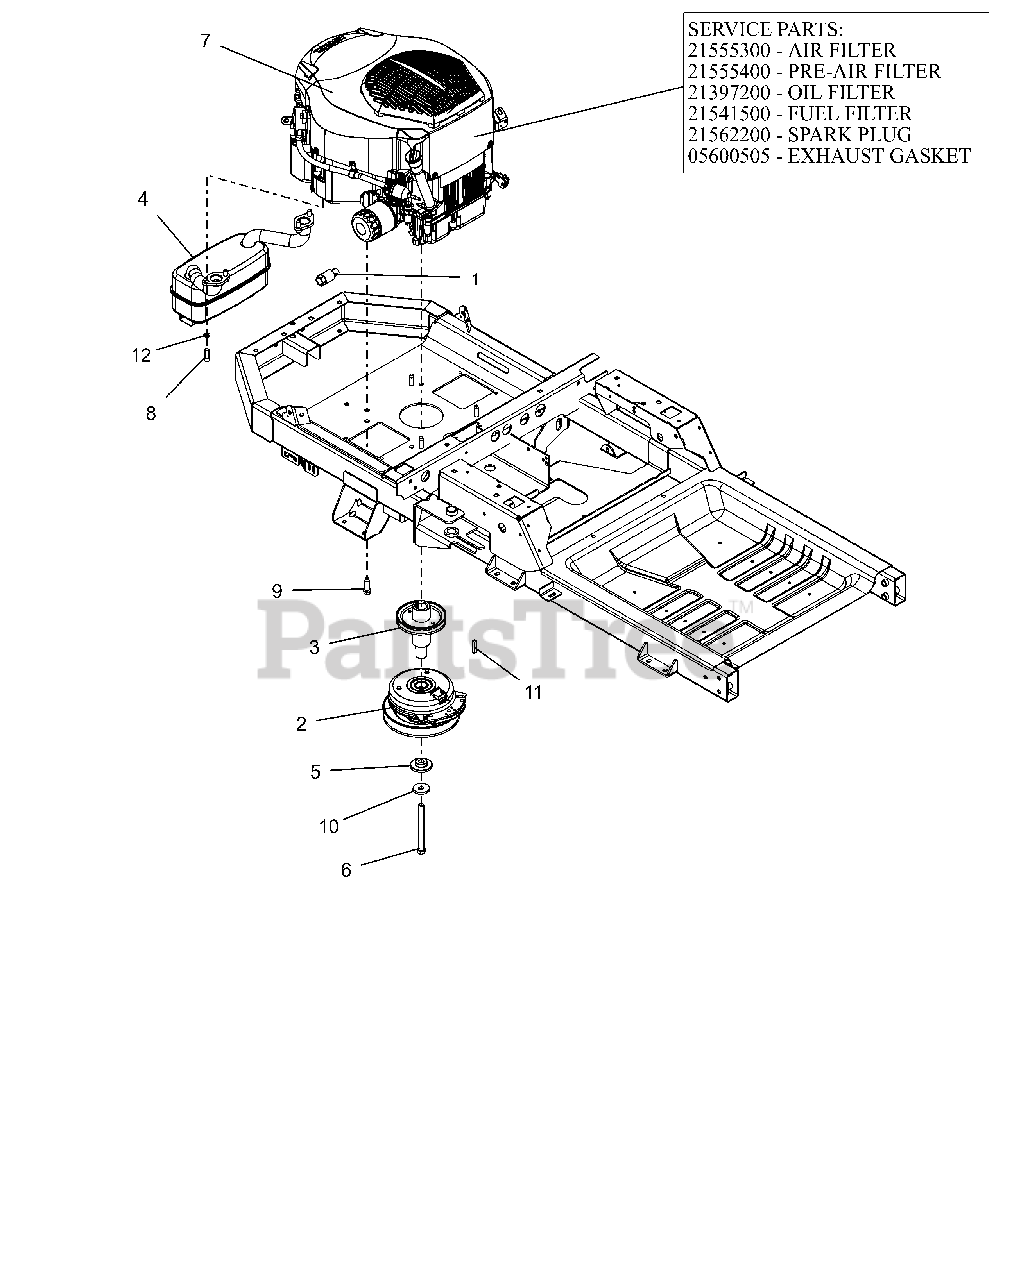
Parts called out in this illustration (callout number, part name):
1	DRAIN, OIL
2	CLUTCH,105FTLB MONOPOLE 6.83"
3	WLDMT, DRIVE SHEAVE (LG XL)CZC
4	MUFFLER - KOHLER
5	BSHG-FLG .469X1.06X.574X2.0
6	BLT-HEX.438-20X5 GR8 YZ NYTORQ
7	ENGINE,KOHLER TWIN 25 PRO W/SC
7	AIR FILTER, KOHLER
7	PRE CLEANER, KOHLER
7	FILTER, OIL - KOH CV20
7	FILTER, FUEL
7	PLUG, SPARK (RFI)
7	GASKET, MUFFLER KOHLER TWIN
8	SCR, SKH .312-18X.875 GR8 ZCC
9	SCR,TAP .375-16X1.25HWH TR ZCC
10	WASHER, 7/16" SPRING DISK
11	KEY-SQ .25 X 1.25 X .25 SAE
12	WSHR,LK-REG .312X.078 ZCC
